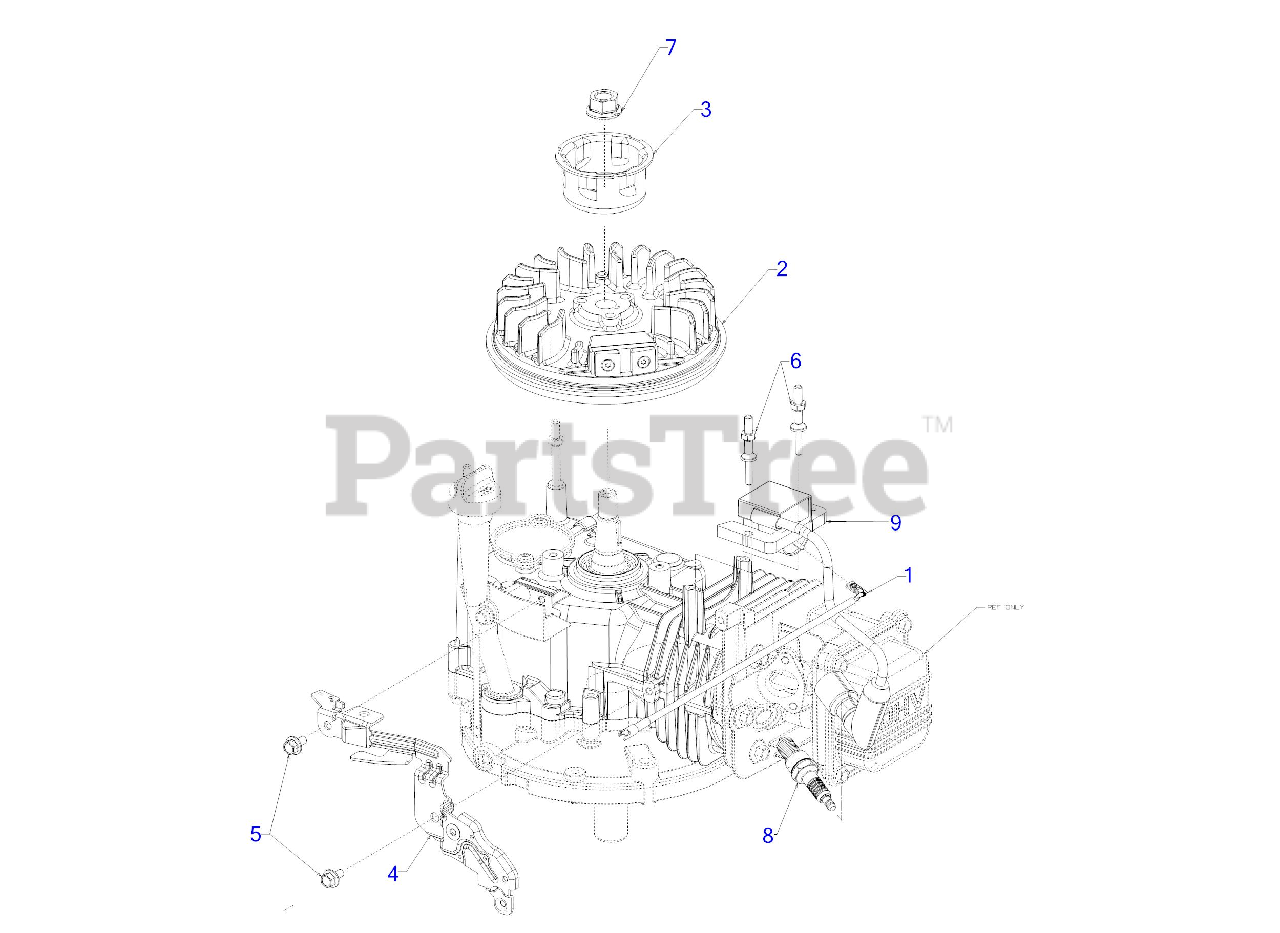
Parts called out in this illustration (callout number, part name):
1	WIRE HARNESS
2	FLYWHEEL ASSEMBLY
4	ENGINE BRAKE SUPPORT BRACKET
5	SCREW M6-1 x 12 CL8.8
6	STUD M5-8:22
7	HEX FLANGE NUT
8	SPARK PLUG
9	IGNITION MODULE
